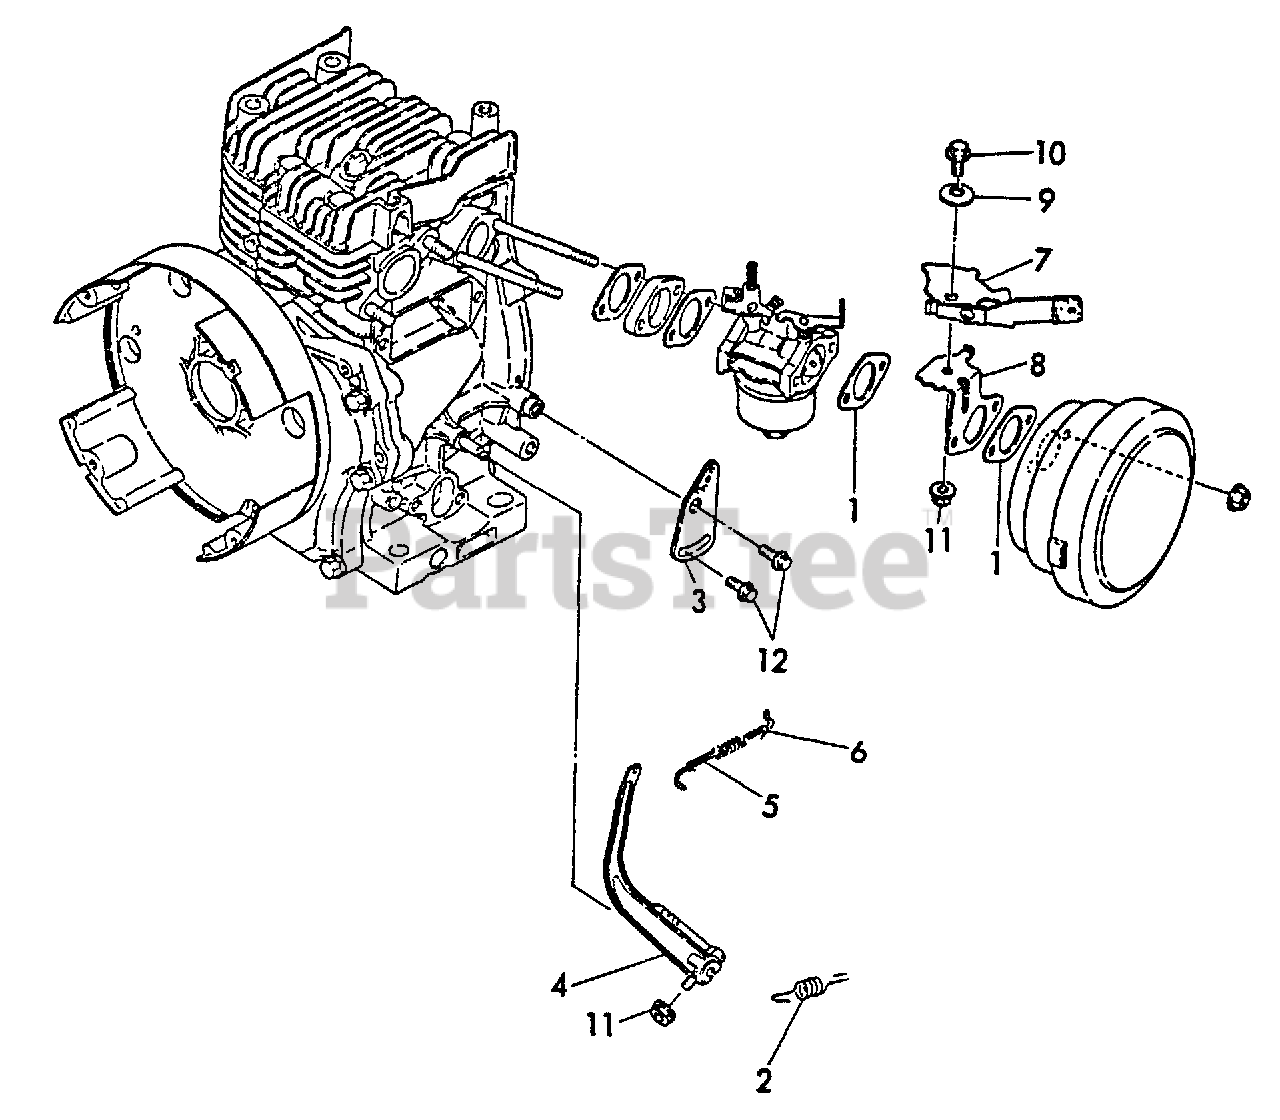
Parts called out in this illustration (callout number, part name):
1	GASKET, INTAKE
2	SPRING, REGULATOR
3	HANDLE, REGULATOR
4	LEVER, GOVERNOR
5	LINK, THROTTLE
6	SPRING, TENSION
7	LEVEL ASSY
8	BRACKET
9	COLLAR
10	BOLT - 6×12 -- PLATED
11	U-NUT M6
12	BOLT - 6×8 -- PLATED
